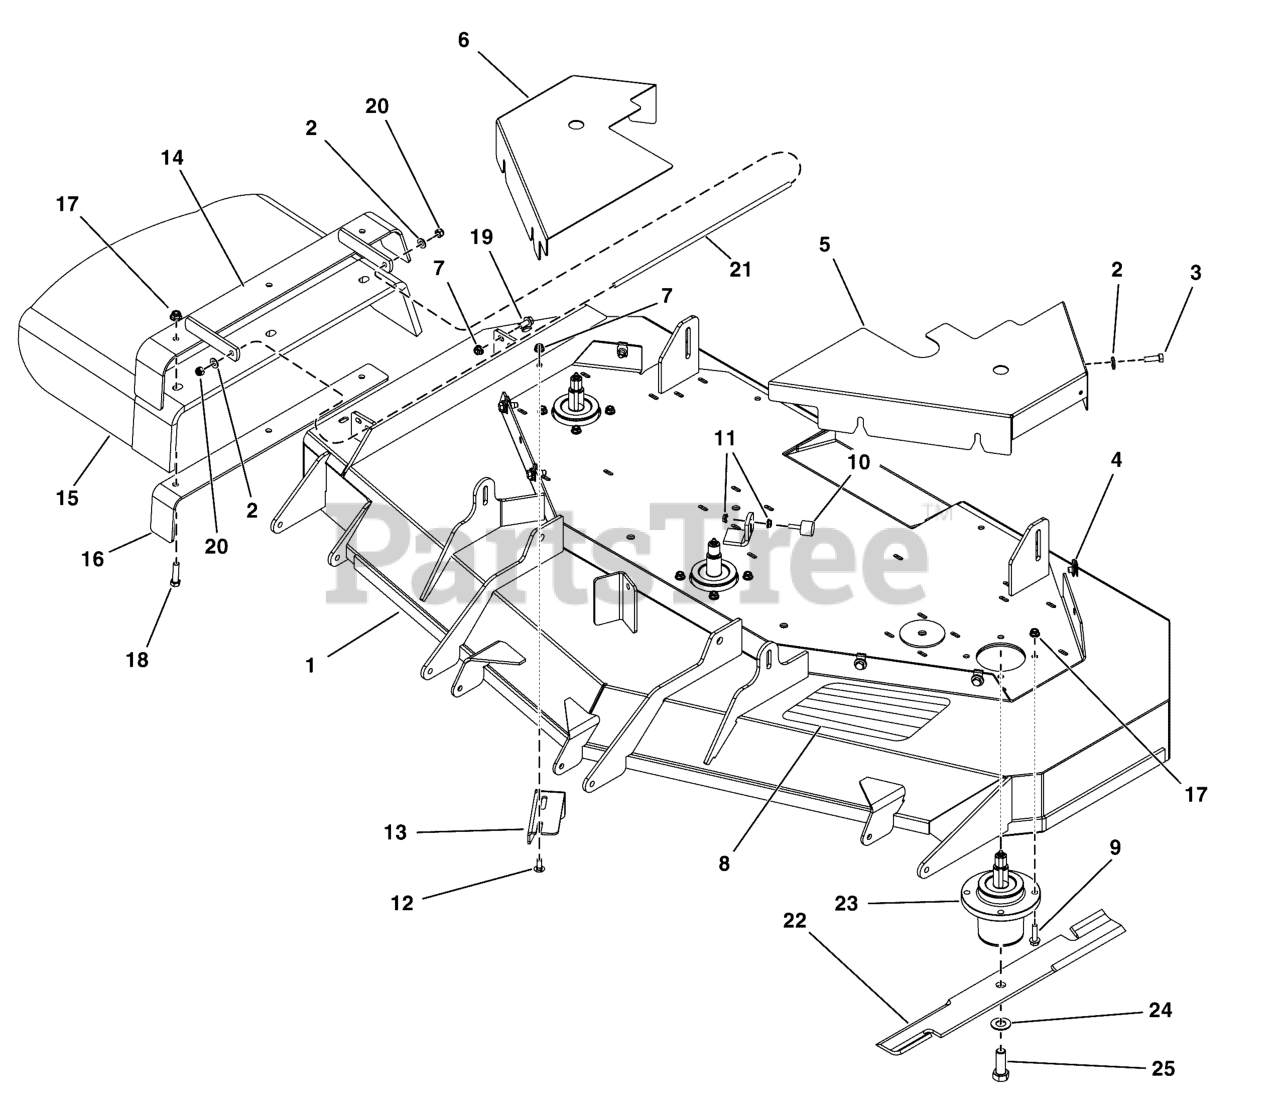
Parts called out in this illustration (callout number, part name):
1	DECK SHELL W/ DECALS, 61, 125 (5415801D)
2	WASHER, 5/16" SAE
3	BOLT, 5/16-18 X 1" GRD5 YZ
4	BODY CLIP, 5/16-18-7GA MATERIAL
5	GUARD 61 - LH - RED
6	PLATE, GUARD, 61, RH - RED
7	NUT, 5/16-18 HEX NYLOCK FLANGE NUT
8	SAFETY WALK, 4.00 X 7.50
9	BOLT, 3/8-16 X 1-1/4, FLANGE, GD 5, CZ
10	BUMPER, RUBBER, 1/4-20 X 7/8" STUD
11	NUT, 1/4-20 HEX SERR. FLANGE
12	BOLT, 5/16-18 X 3/4, CARRIAGE, GD5, CZ
13	PLATE, DEFLECTOR - BLK
15	CHUTE, RUBBER DISCHARGE (5104442)
16	SUPPORT, DISCHARGE CHUTE - BLK
17	NUT, 3/8 - 16 HEX NYLOCK FLANGE
18	BOLT, 3/8-16 X 1-1/2, CARRIAGE, GD5, CZ
19	BOLT, 5/16-18 X 3/4 GD5
20	NUT, 5/16-24 HEX NYLON LOCK
21	ROD, MOUNT, CHUTE, 61, CZ
22	BLADE SET, 61 DECK (3)
23	SPINDLE, ASSM, ALUMINUM - 5.25
24	WASHER, BLADE BOLT, 9/16" F436, CZ
25	BOLT, 5/8-11 X 1-3/4 GD8
